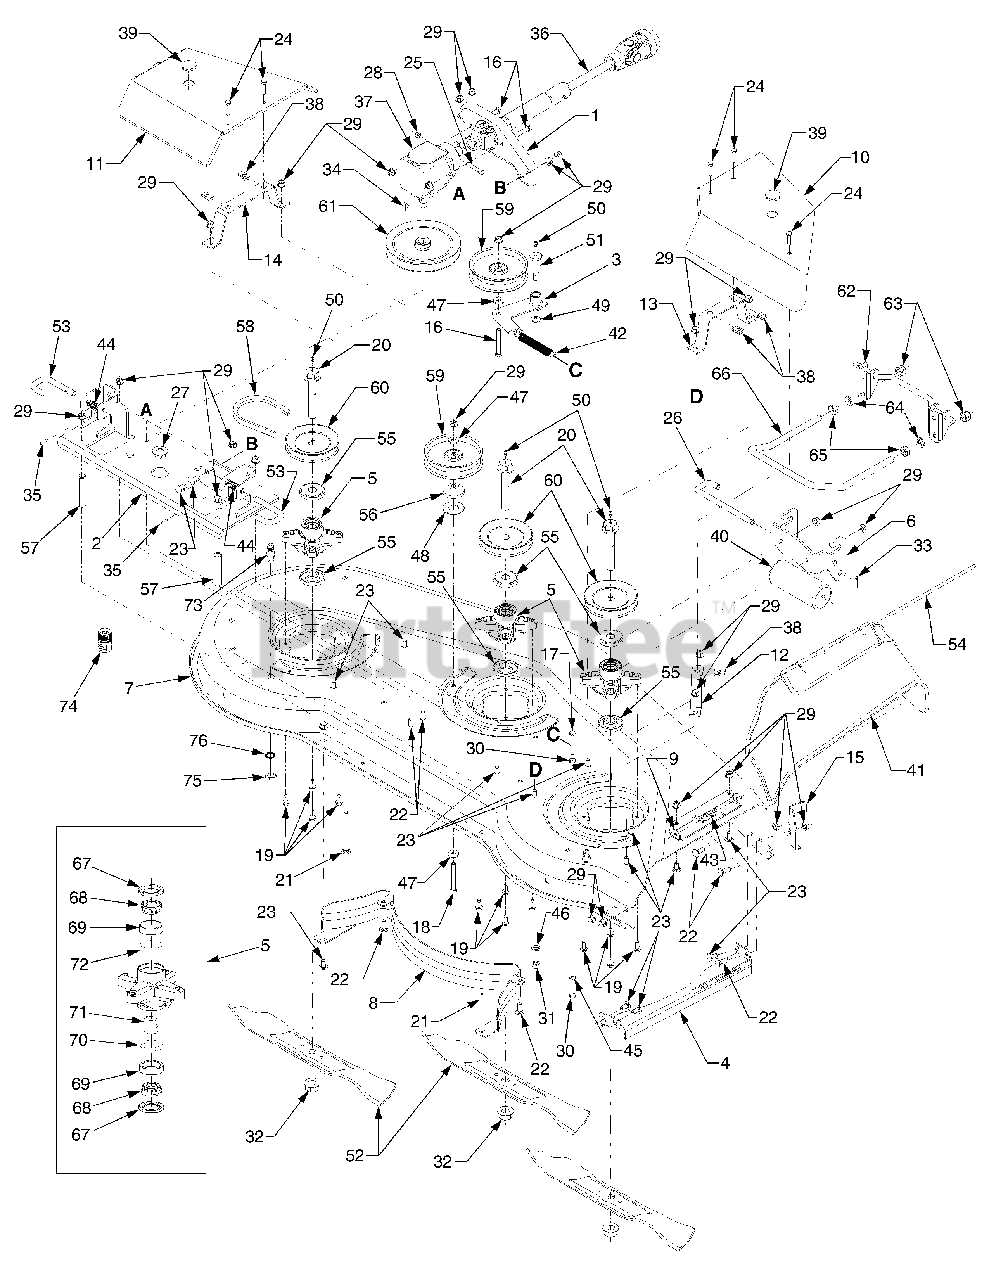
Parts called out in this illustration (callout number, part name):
1	Bracket Assembly,Drive
2	Bracket Assembly, Mounting for decks built Mfg. Date 1K019G and after
2	Bracket Assembly, Mounting for decks built Mfg. Date 1J319G and before
3	Bracket Assembly, Idler for decks built Mfg. Date 1K019G and after
3	Bracket Assembly, Idler for decks built Mfg. Date 1J319G and before
4	Guard, Deck, Opening for decks built Mfg. Date 1K019G and after
4	Guard, Deck, Opening for decks built Mfg. Date 1J319G and before
5	Assembly, Spindle - Replaces all older spindles.
6	Bracket, Roller, Front for decks built Mfg. Date 1K019G and after
6	Bracket, Roller, Front for decks built Mfg. Date 1J319G and before
7	Housing, Deck (w/o Deck wash holes)for decks built Mfg. Date 1K019G and after
7	Housing, Deck (w/o Deck wash holes)for decks built Mfg. Date 1J319G and before
7	Housing, Deck (w/ Deck wash holes)
7	Label, 60"
7	Label, Danger R.H. Side of Deck
7	Label, Danger L.H. Side of Deck
8	Baffle, Deck- for decks built Mfg. Date 1K019G and after
8	Baffle, Deck- for decks built Mfg. Date 1J319G and before
9	Bracket, Deck, Chute- for decks built Mfg. Date 1K019G and after
9	Bracket, Deck, Chute- for decks built Mfg. Date 1J319G and before
10	Cover, Belt -R.H.- for decks built Mfg. Date 1K019G and after
10	Cover, Belt -R.H.- for decks built Mfg. Date 1J319G and before
11	Cover, Belt - L.H.- for decks built Mfg. Date 1K019G and after
11	Cover, Belt - L.H.- for decks built Mfg. Date 1J319G and before
12	Bracket, Belt Cover- R.H.- for decks built Mfg. Date 1K019G and after
12	Bracket, Belt Cover- R.H.- for decks built Mfg. Date 1J319G and before
13	Bracket, Belt Cover - Center- for decks built Mfg. Date 1K019G and after
13	Bracket, Belt Cover - Center- for decks built Mfg. Date 1J319G and before
14	Bracket, Belt Cover - L.H.- for decks built Mfg. Date 1K019G and after
14	Bracket, Belt Cover - L.H.- for decks built Mfg. Date 1J319G and before
15	Stop, Chute Deflector- for decks built Mfg. Date 1K019G and after
15	Stop, Chute Deflector- for decks built Mfg. Date 1J319G and before
16	Screw, Hex Cap 3/8-16 x 1.75" GR5
17	Screw, Hex Cap 5/16-18 x 2.25" GR5
18	Screw, Hex Cap, 3/8-16 x 3.0" GR8
19	Screw, Hex Wash. Hd. Tapp 5/16-18 x .75"
20	Bolt, Spindle 3/4-16 x 4.25"
21	Bolt, Carriage 3/8-16 x 4.50" GR5
22	Bolt, Carriage 3/8-16 x 1"
23	Bolt, Carriage 3/8-16 x .75"
24	Screw, HHC, 5/16-18 x 1.0 GR5 (Replaces 710-3232 Thmb Scrw)
25	Screw, Socket Hd. 5/16-18 x 1.75"
26	Pin, Roller 1/2 x 7.31"
27	Nut, Hex Flanged 5/8-18
28	Nut, Hex Lock 5/16-18
29	Nut, Flange Lock 3/8-16
30	Nut, Hex 5/16-18
31	Nut, Hex 7/16-14
32	Nut, Hex Flange 3/4-16
33	Pin, Cotter 1/8 x 1.0
34	Key, Hi-Pro
35	Pin, Spirol
36	Shaft, Drive
37	Drive, Right Angle
38	Nut, "U" 5/16-18
39	Plug, Button
40	Roller, Front
41	Deflector, Chute
41	Label, Danger
42	Spring, Extension 5.06" Lg.
43	Spring, Torsion
44	Spring, Compression
45	Washer, Lock, 5/16
46	Washer, Lock 7/16" I.D.
47	Washer, Flat, .385 x 1.0 x .13
48	Washer, Flat, 1.010 x 2.0 x .065
49	Washer, Flat, .469 x .875 x .105
50	Fitting, Grease
51	Bolt, Shoulder .68" x 1.59
52	Blade 20.5" Lg.
53	Pin, Mower Support
54	Rod, Chute Deflector
55	Spacer, Spindle
56	Spacer, Idler
57	Spacer, .5" I.D. x .75" O.D.
58	"V"- Belt 124" Lg.
59	Pulley, Idler
60	Pulley, Spindle
61	Pulley, Drive
62	Bracket, Front Lift
63	Nut, Hex Lock 5/8-11
64	Washer, Lock 5/8" I.D.
65	Nut, Hex Lock 5/8-11
66	Rod, Front Lift
67	Seal, Oil
68	Bearing, Cone - Mfg. Code 1I173G and before
68	Bearing, Cone - Mfg Code 1I183G and after
69	Cup, Bearing - Mfg. Code 1I173G and before
69	Cup, Bearing - Mfg. Code 1I183G and after
70	Spacer, Brng.
71	Spacer, Bearing - Mfg. Code 1I173G and before
71	Spacer, Bearing - Mfg. Code 1I183G and after
72	Spacer, Brng
73	Nozzle, Deck Wash - Mfg. Code 1J014G and after
74	Adapter, Nozzle - Mfg. Code 1J014G and after
75	Nut, Hex, M16-1.5 - Mfg. Code 1J014G and after
76	Washer, Lock - Mfg. Code 1J014G and after
